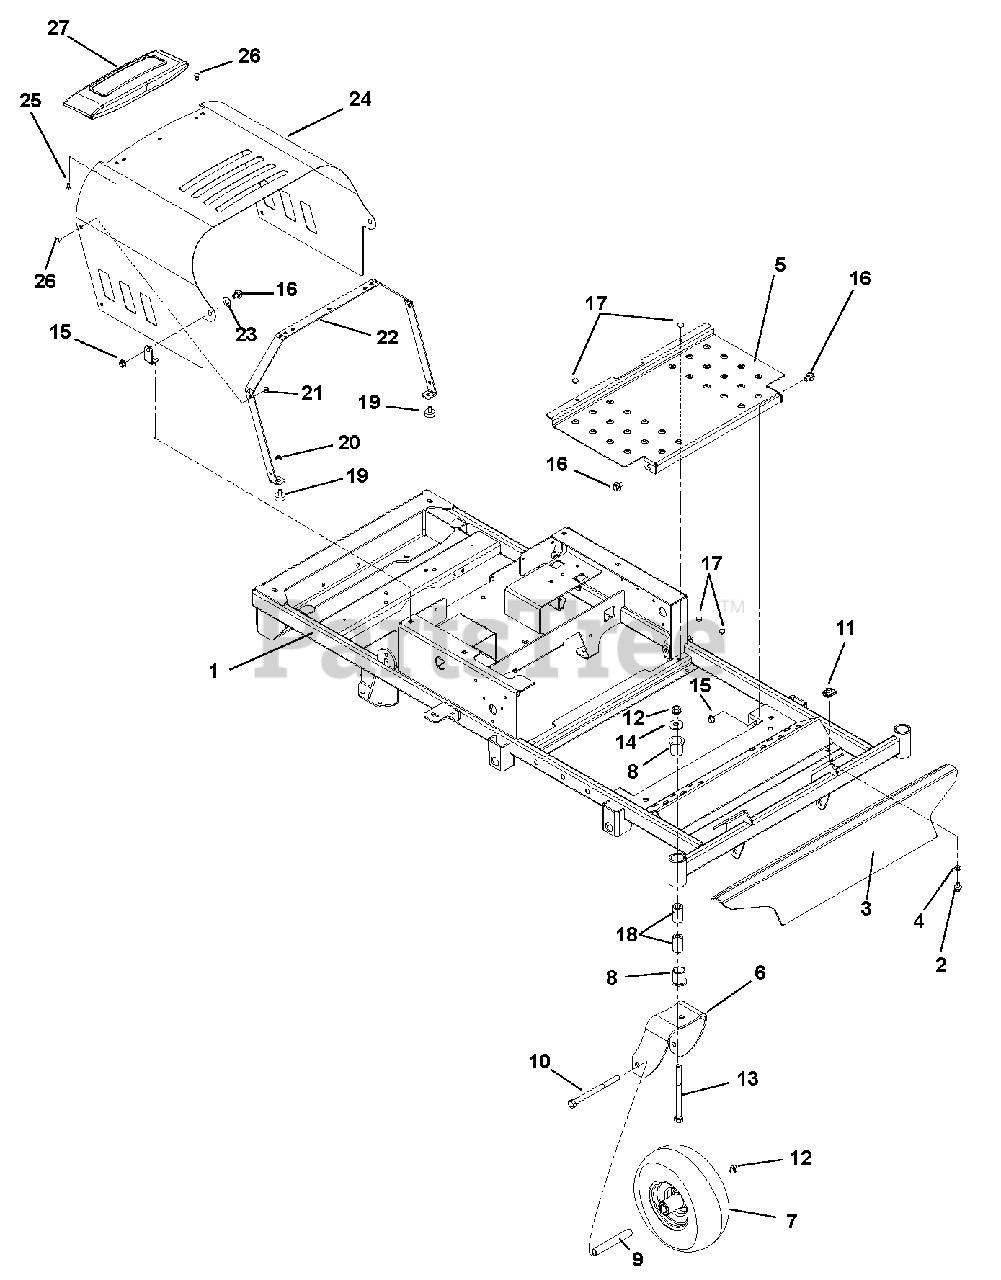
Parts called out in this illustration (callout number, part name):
1	WLDMT, FRAME ZT/ZOOMXL (2013)
2	@BLT-HEX .38-16X1.00 GR5 YWZC
3	WMT, FOOTREST
4	@WSHR-LK .38X.094 REG YWZC
5	DECK ACCESS PANEL
6	WMT, CASTER FORK
7	TIRE/WHEEL ASSY, 11X4-5
8	BSHG-FLG 1.00X1.25X1.50X1.50
9	SPACER, ROLLED WHEEL
10	@BLT-HEX .50-13X6.50 GR5 YWZC
11	NUT-RTNR .375-16X.37
12	@NUT-LK-TOP-FLG .50-13 YWZC
13	@BLT-HEX .50-13X5.00 GR5 YWZC
14	WSHR-FL-STL.511X1.441X.125 YWZ
15	@NUT-LK-TOP-FLG .38-16 YWZC
16	BOLT-SHLDR .375-16X.150
17	BUMPER GROMMET
18	SPACER, CASTER .50X1.00X1.84
19	BUMPER, RUBBER
20	@NUT-SPNLK-FLG .312-18 YWZC
21	@NUT-LK-TOP-FLG .25-20 YWZC
22	HOOD STRAP
23	WSHR-FL-NYL .518X1.000X.080
24	HOOD, XL
25	SCR-HEX .25X14-.75
26	@BLT-RDHDSQNK .25-20X.50 G5YZ
27	TRIM-ZOOM XL HOOD ARIENS
